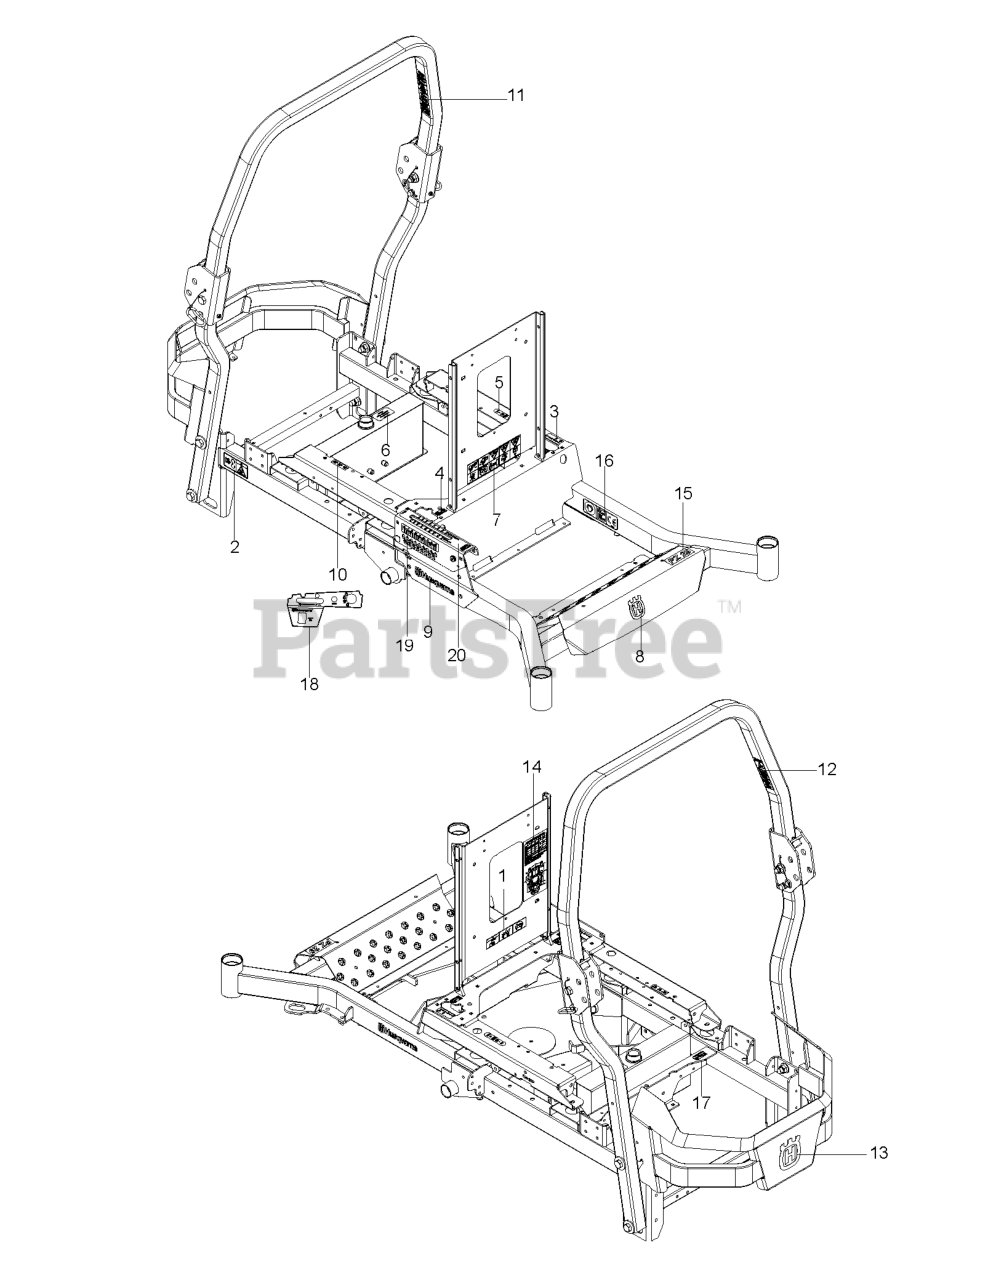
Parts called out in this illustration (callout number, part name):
1	EURO DECAL-BATTERY WARNIN6
2	DECAL, BELT DRIVE
3	DECAL, MOTION CONTROL
4	DECAL, F.S.T.
5	DECAL, PARK BRAKE
6	DECAL, OIL TANK
7	DECAL, WARNING
8	DECAL.AUGER.HUSQ.CROWN.SNOW
9	RP.DECAL.BADGE.170MM.TEXTLOGO
10	DECAL, FUSE
11	DECAL, ROPS
12	DECAL, ROPS, WARNING
13	DECAL, CROWN H, 110MM
14	DECAL, SERVICE
15	DECAL, PZ29
17	DECAL, FUEL
18	DECAL, CONTROL, GAS
19	DECAL, HEIGHT CE
20	DECAL, HEIGHT CE
